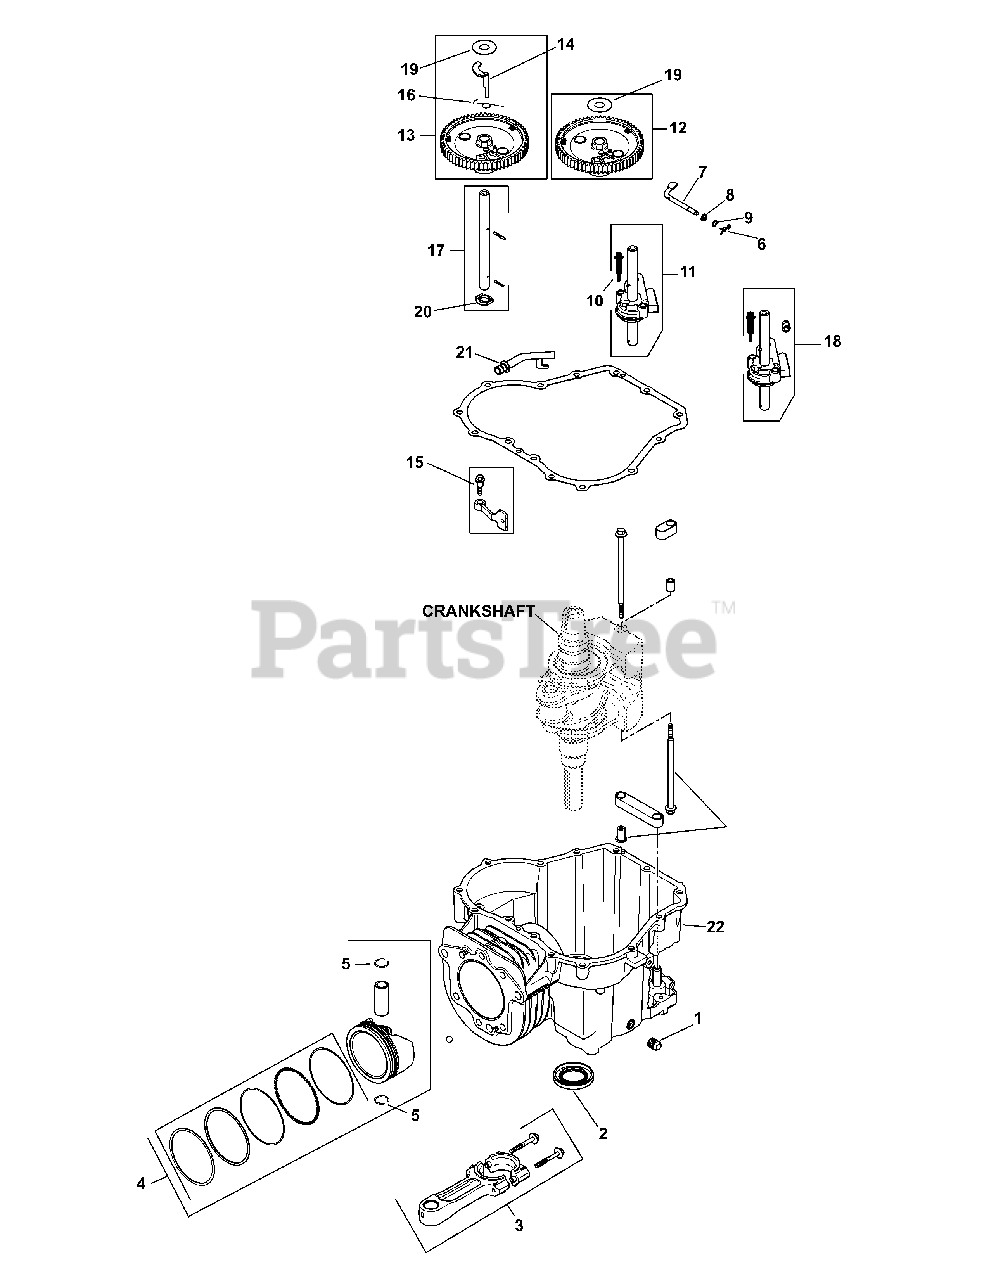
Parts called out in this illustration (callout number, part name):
1	Square Head Pipe Plug, 3/8
3	Connecting Assembly Rod
4	Piston W/ Ring Set Kit, 94mm
5	Piston Pin Retainer
6	Hitch Pin Clip
7	Governor Cross Shaft
8	Flat Washer, 6 Mm
9	Flat Washer, 1/4
10	Shd. Thd. Frm. Screw
11	Oil Pump Assembly Kit
12	Cam Lobe Assembly
13	Cam Gear Assembly
14	Acr. Weight and Follower Kit
15	Shd. Thd. Frm. Screw, M6 x 1 x 26
17	Cam Center Shaft Kit
18	Oil Pump Kit (Shallow 10mm)
19	Thrust -Acr. Washer
20	Thrust Washer
21	Drainback Tube
22	Crankcase (Use: Short Block)
